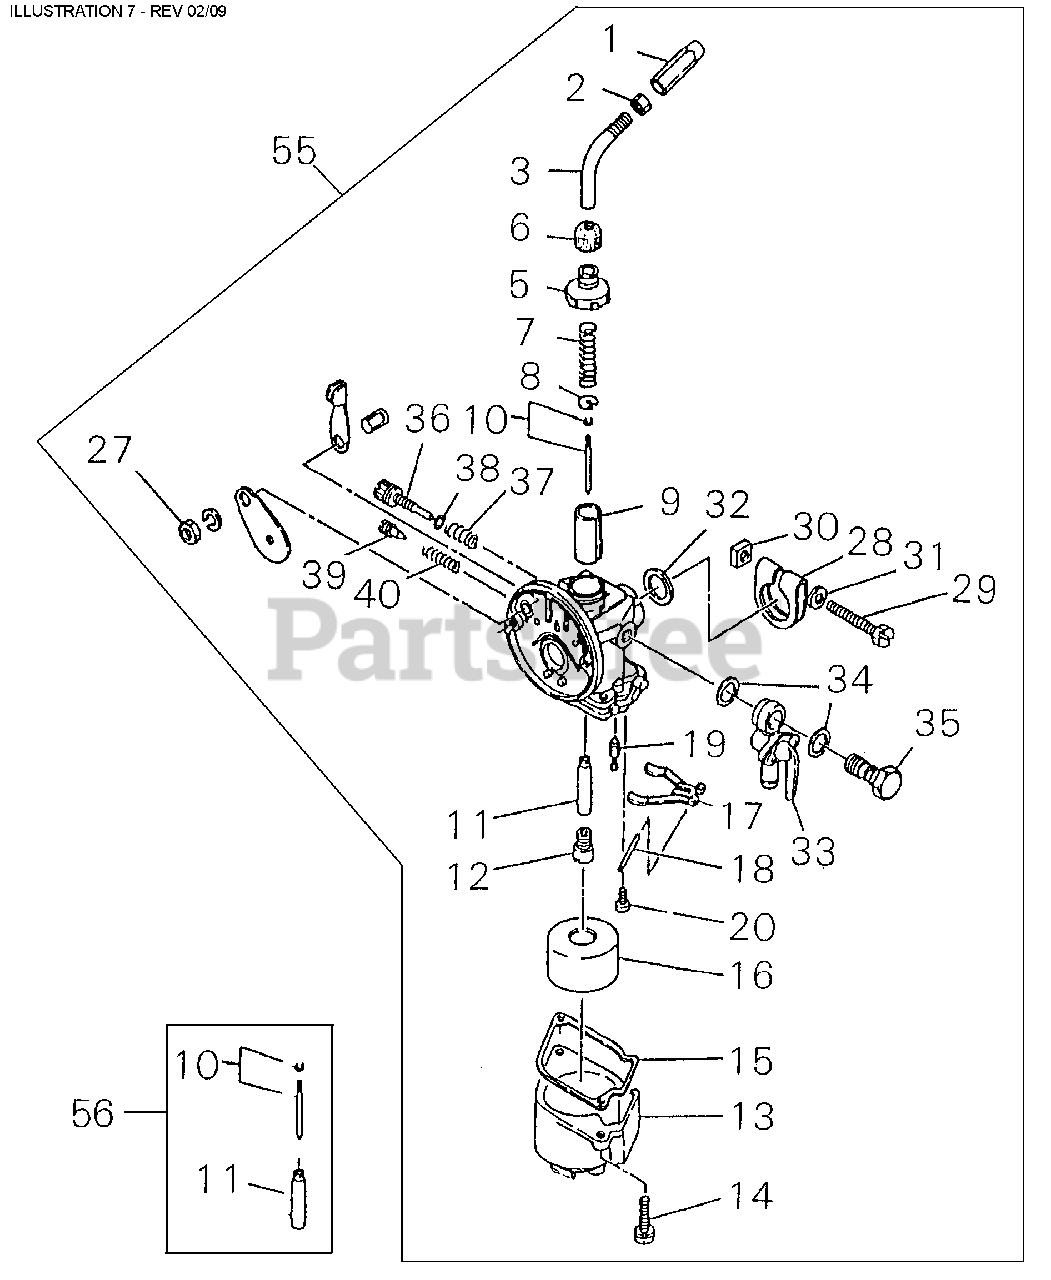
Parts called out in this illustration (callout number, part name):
1	NUT, CABLE ADJUST
2	LOCKNUT
3	GUIDE, CABLE
5	CAP, CARBURETOR
6	GROMMET
7	SPRING, THROTTLE
8	RETAINER
9	VALVE, THROTTLE
10	NEEDLE, JET
11	VALVE, INLET NEEDLE
12	JET, MAIN
13	CHAMBER, FLOAT
15	GASKET
16	FLOAT
17	HINGE, FLOAT
18	PIN, HINGE
19	VALVE, INLET NEEDLE
20	SCREW
27	LOCKNUT
28	CLAMP
29	BOLT
31	WASHER
32	SEAL
33	COCK, FUEL
34	GASKET
35	BOLT - BANJO
36	SCREW, SLOW STOP
37	SPRING
38	O-RING
39	SCREW, SLOW AIR
40	SPRING
55	CARBURETOR
56	JET NEEDLE KIT
